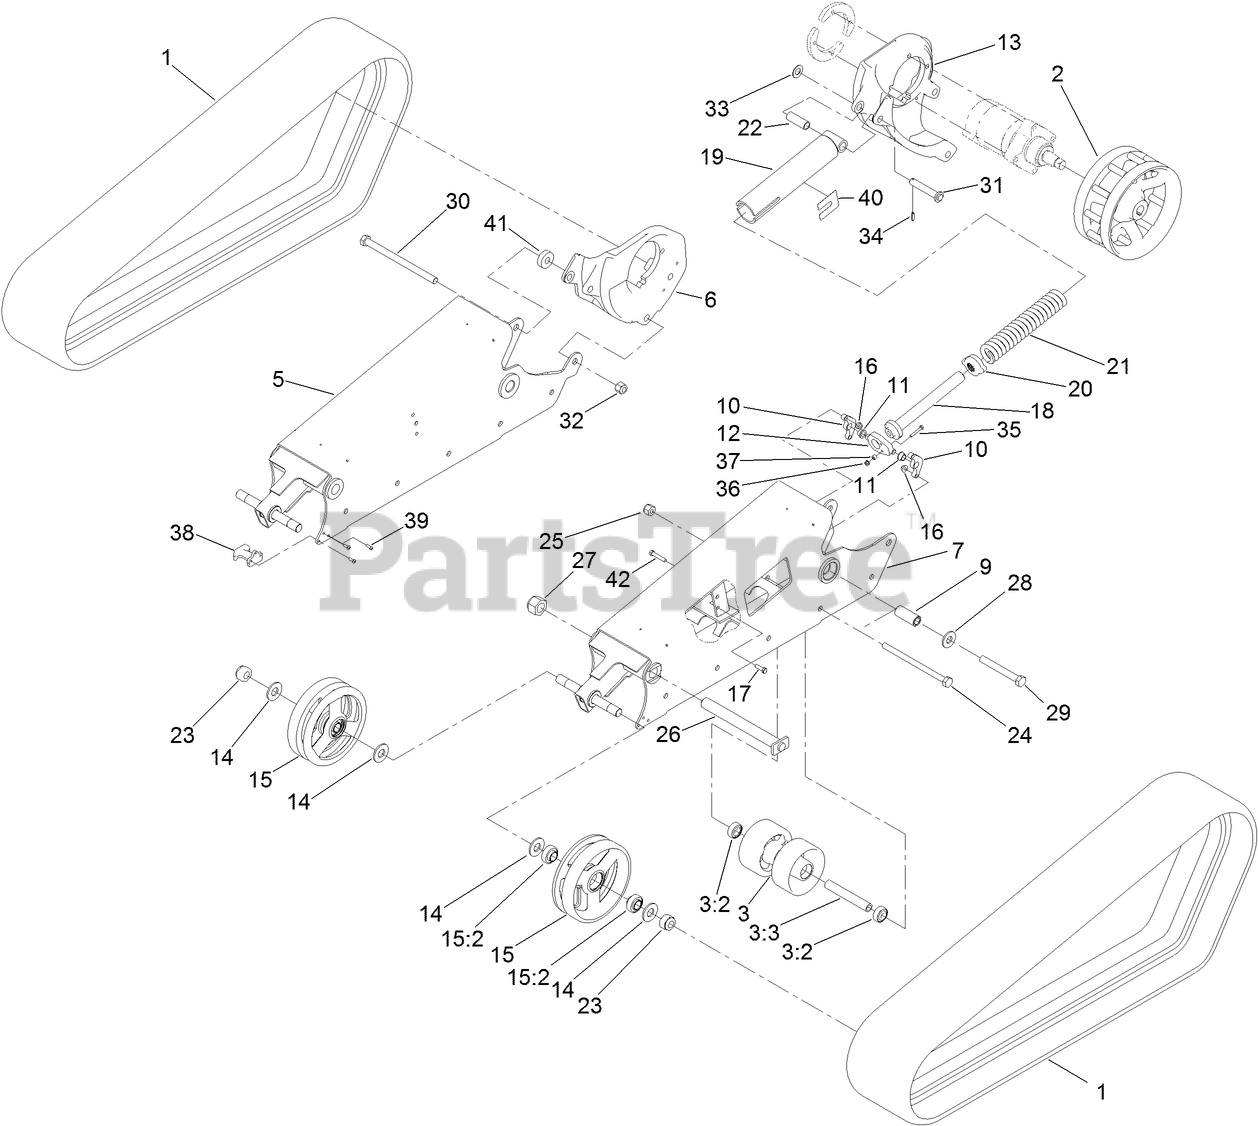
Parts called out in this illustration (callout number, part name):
1	TRACK-WIDE
2	WHEEL-DRIVE
3	WHEEL ASM
3:2	BEARING-BALL
3:3	SPACER-WHEEL, ROAD
5	RH TRACK GUIDE ASM
6	MOUNT-MOTOR, RH
7	LH TRACK GUIDE ASM
9	SPACER
10	PLATE-MOUNT, PIVOT
11	BUSHING-BELLCRANK
12	PLATE-PIVOT
13	MOUNT-MOTOR, LH
14	WASHER-PLAIN
15	TENSIONER-WHEEL
15:2	Bearing-Ball
16	NUT-HF, NI
17	SCREW-HH
18	BOLT-TENSIONER
19	PIVOT-TENSIONER
20	BLOCK-TENSIONER
21	SPRING-COMPRESSION
22	SPACER-PIVOT
23	NUT-HEX, NI
24	SCREW-HH
25	NUT-HEX
26	PIN-TRACK
27	NUT-HH
28	WASHER
29	SCREW-HH
30	SCREW-HH
31	PIN-TENSIONER
32	NUT-LOCK, NI
33	WASHER-FLAT
34	PIN-SPRING
35	SCREW-HH
36	NUT-HHF
37	SPACER
38	TRACK-GUIDE
39	SCREW-HSBH
40	DECAL-INDICATOR, TENSIONER
41	SPACER-WHEEL, MOUNT
42	SCREW-HH
